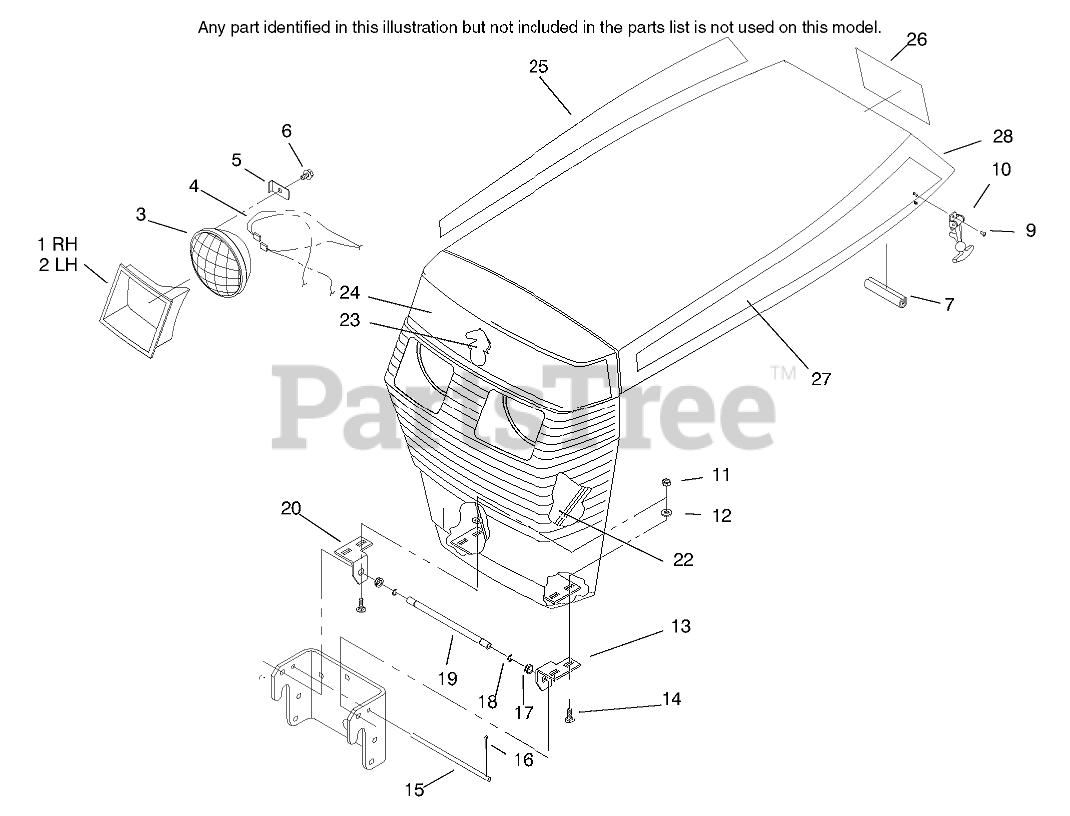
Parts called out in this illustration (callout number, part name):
1	BEZEL-HEADLIGHT, LH
2	BEZEL-HEADLIGHT, RH
3	HEADLAMP
4	HARNESS-HEADLIGHT
5	LOCK-HEADLIGHT
6	SCREW-HWH
7	EDGING-CONSOLE
9	RIVET-POP
10	HANDLE ASM
11	NUT-LOCK, NI
12	WASHER-FLAT
13	BRACKET-GRILL, LH
14	SCREW-CARR
15	ROD-HOOD STOP
16	PIN-COTTER
17	BUSHING-NYLINER
18	RING-RETAINING
19	ROD-GRILL PIVOT
20	BRACKET-GRILL, R H
22	TIE-CABLE
23	LOGO - HORSEHEAD
24	DECAL-FRONT HOOD, TOP
25	DECAL - RH HOOD TOP
26	DECAL-DANGER, HOOD
27	DECAL - LH HOOD TOP
28	Hood
